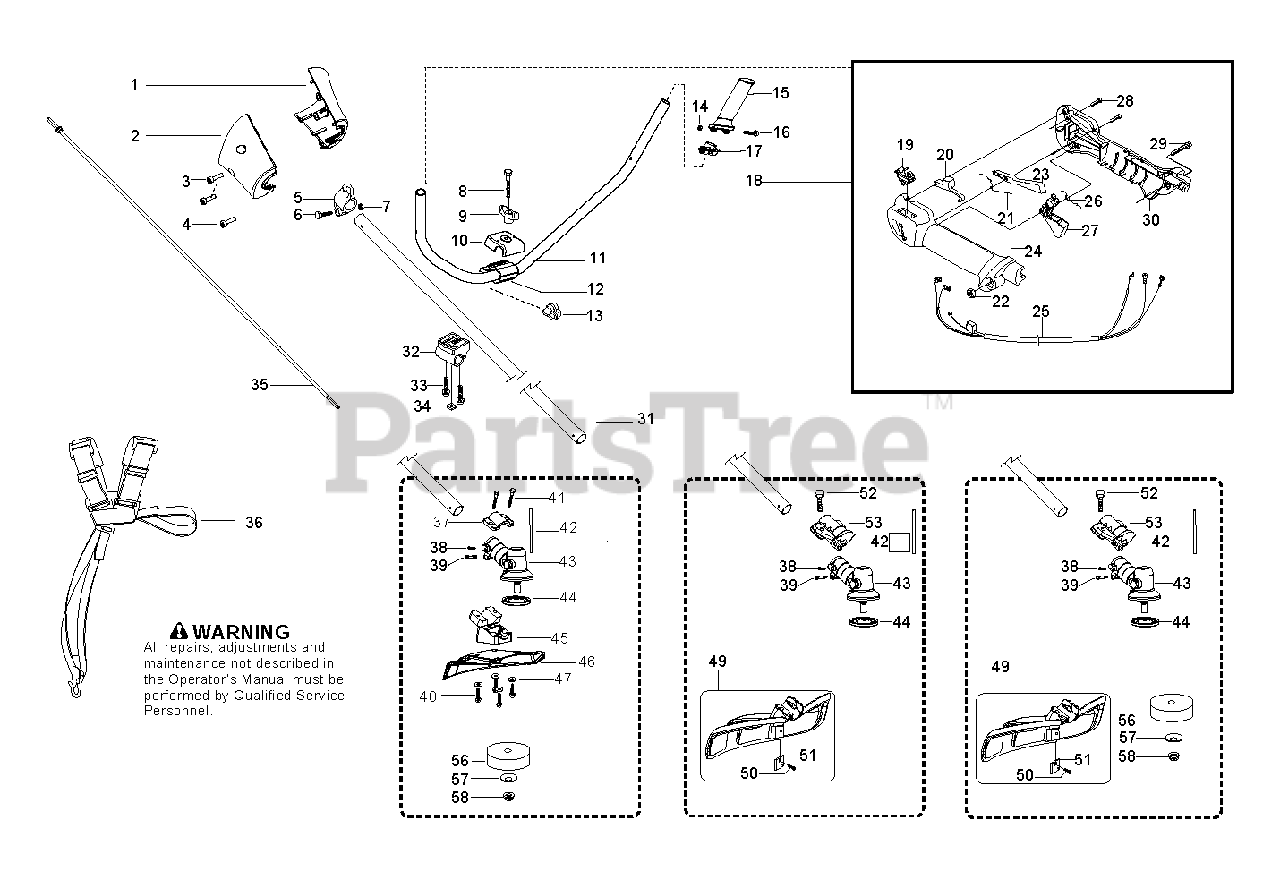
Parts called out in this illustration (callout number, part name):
4	SCREW M4 X 1.75 PT 16MM
12	HOLDER
19	STOP BUTTON
23	TRIGGER SAFETY
25	ASSY CABLE WIRE HARNESS
27	TRIGGER
29	%SCREW
41	BOLT FLANGE - M6X20
42	LOCKING PIN
44	DRIVE DISC
46	METAL GUARD 200MM
47	WASHER 5.3X12
51	LINE CUTTER
53	RP BRACKET TRIMMER GUARD
56	SUPPORTING CUP
57	SUPPORT FLANGE
58	GEARHEAD NUT - BRUSHCUTTER
